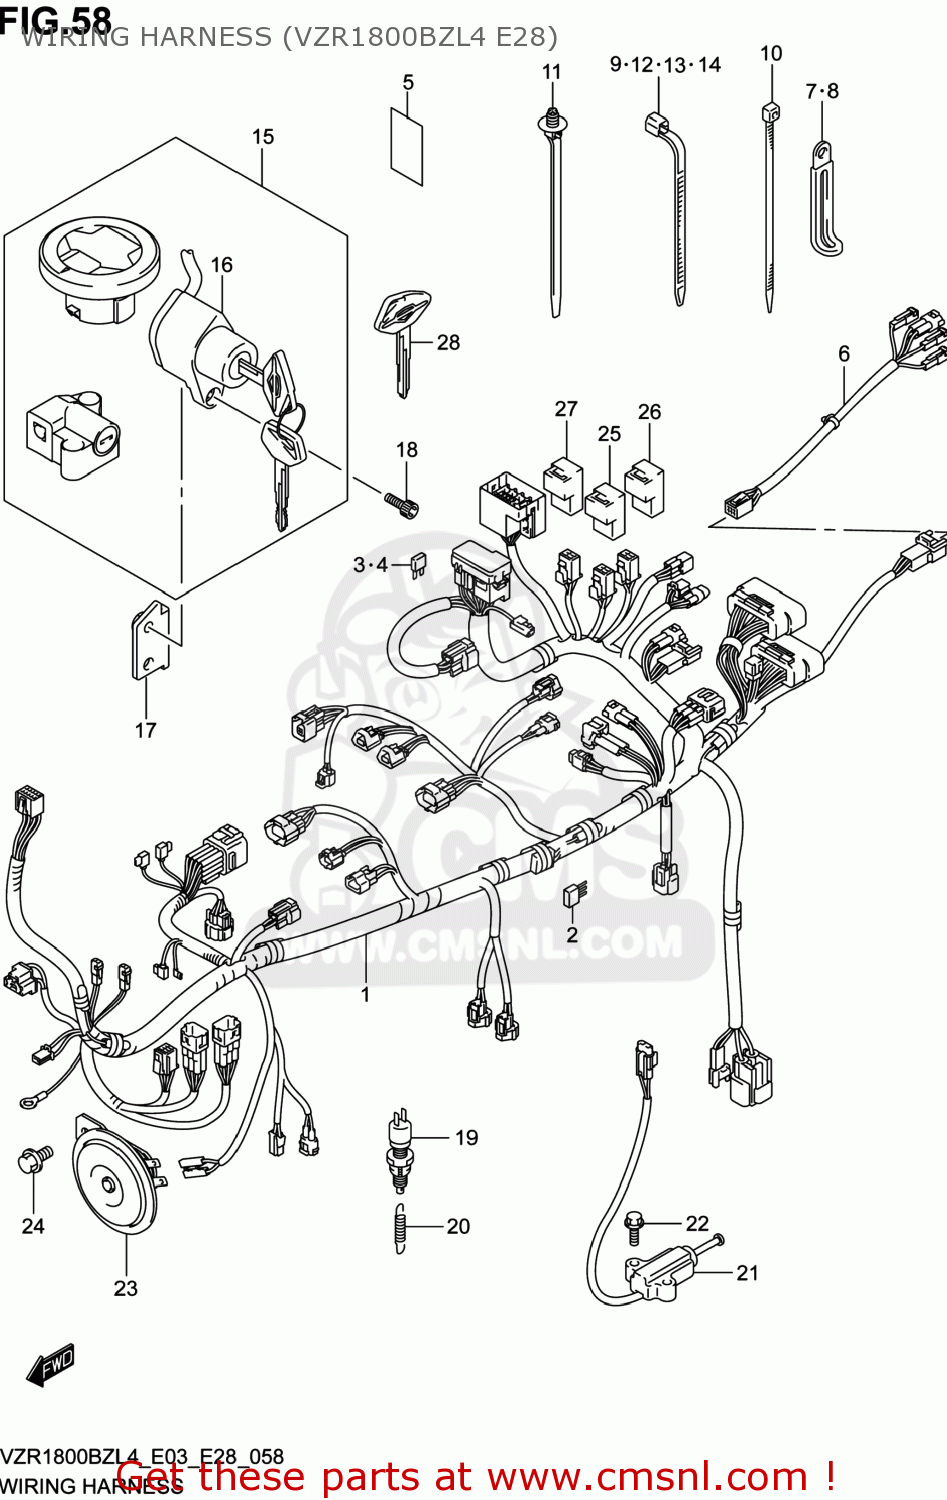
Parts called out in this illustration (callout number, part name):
1	HARNESS,WIRING
2	DIODE(STANLEY DE8804)
3	FUSE(10A)
4	FUSE(15A)
5	TAPE,WIRING HARNESS(28X50X0.13
6	WIRE,RR COMB
7	CLAMP(L:45)
8	CLAMP(L:45)
9	CLAMP(L:125)
10	CLAMP(L:145)
11	CLAMP(L:154)
12	CLAMP(L:165)
13	CLAMP(L:190)
14	CLAMP(L:235)
15	LOCK SET
16	SWITCH ASSY,IGNITION
17	BRACKET,IGNITION SWITCH
18	BOLT
19	SWITCH ASSY,STOP LAMP
20	SPRING
21	SWITCH ASSY,SIDE STAND
22	BOLT
23	HORN ASSY
24	BOLT
25	RELAY ASSY
26	RELAY ASSY
27	RELAY ASSY
28	KEY,BLANK(BOULEVARD)
